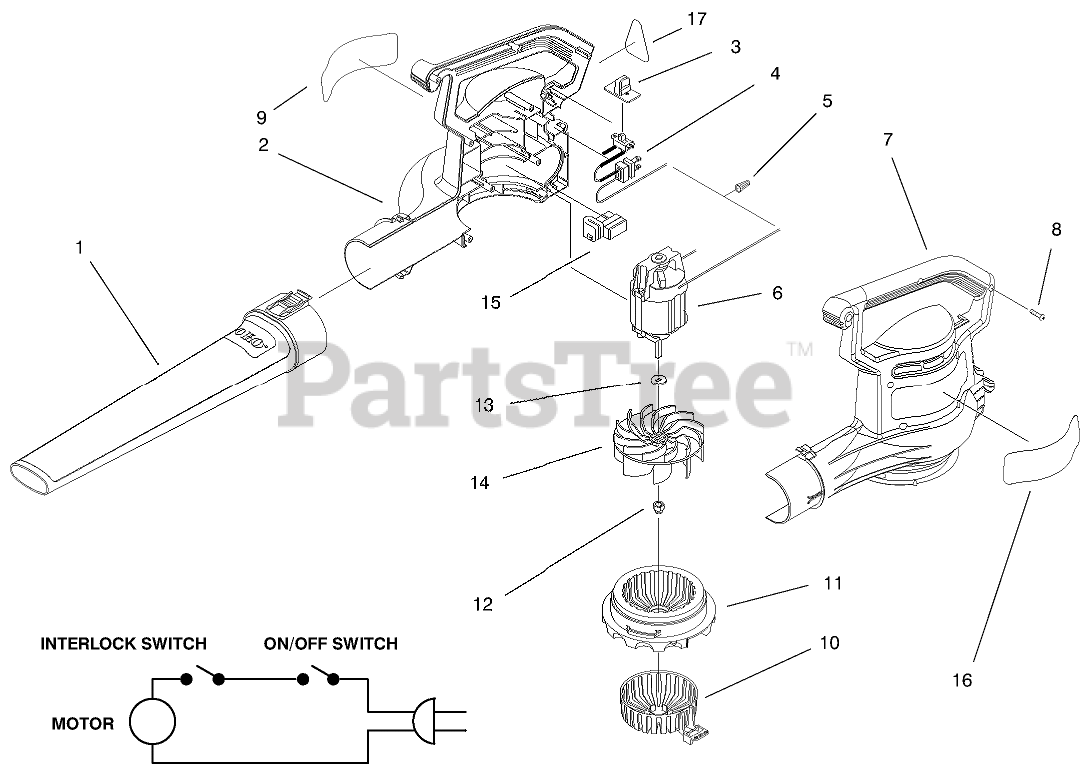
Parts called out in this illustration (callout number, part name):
1	TUBE - BLOWER SHORT
2	HOUSING, RH (RED)
3	COVER-SWITCH
4	HARNESS ASSEMBLY
5	CONNECTOR-NUT, WIRE
6	MOTOR, ES-40, MID-BLOWER
7	HOUSING, LH (RED)
8	SCREW-PPH
9	DECAL, LOGO, AIR RAKE
10	CHOKE - AIR, GREY
11	COVER - INLET, W/HOLE
12	NUT-HEX
13	WASHER
14	IMPELLER, BLOWER
15	SWITCH, INTERLOCK
16	Decal-Warning
17	DECAL - INFORMATION
